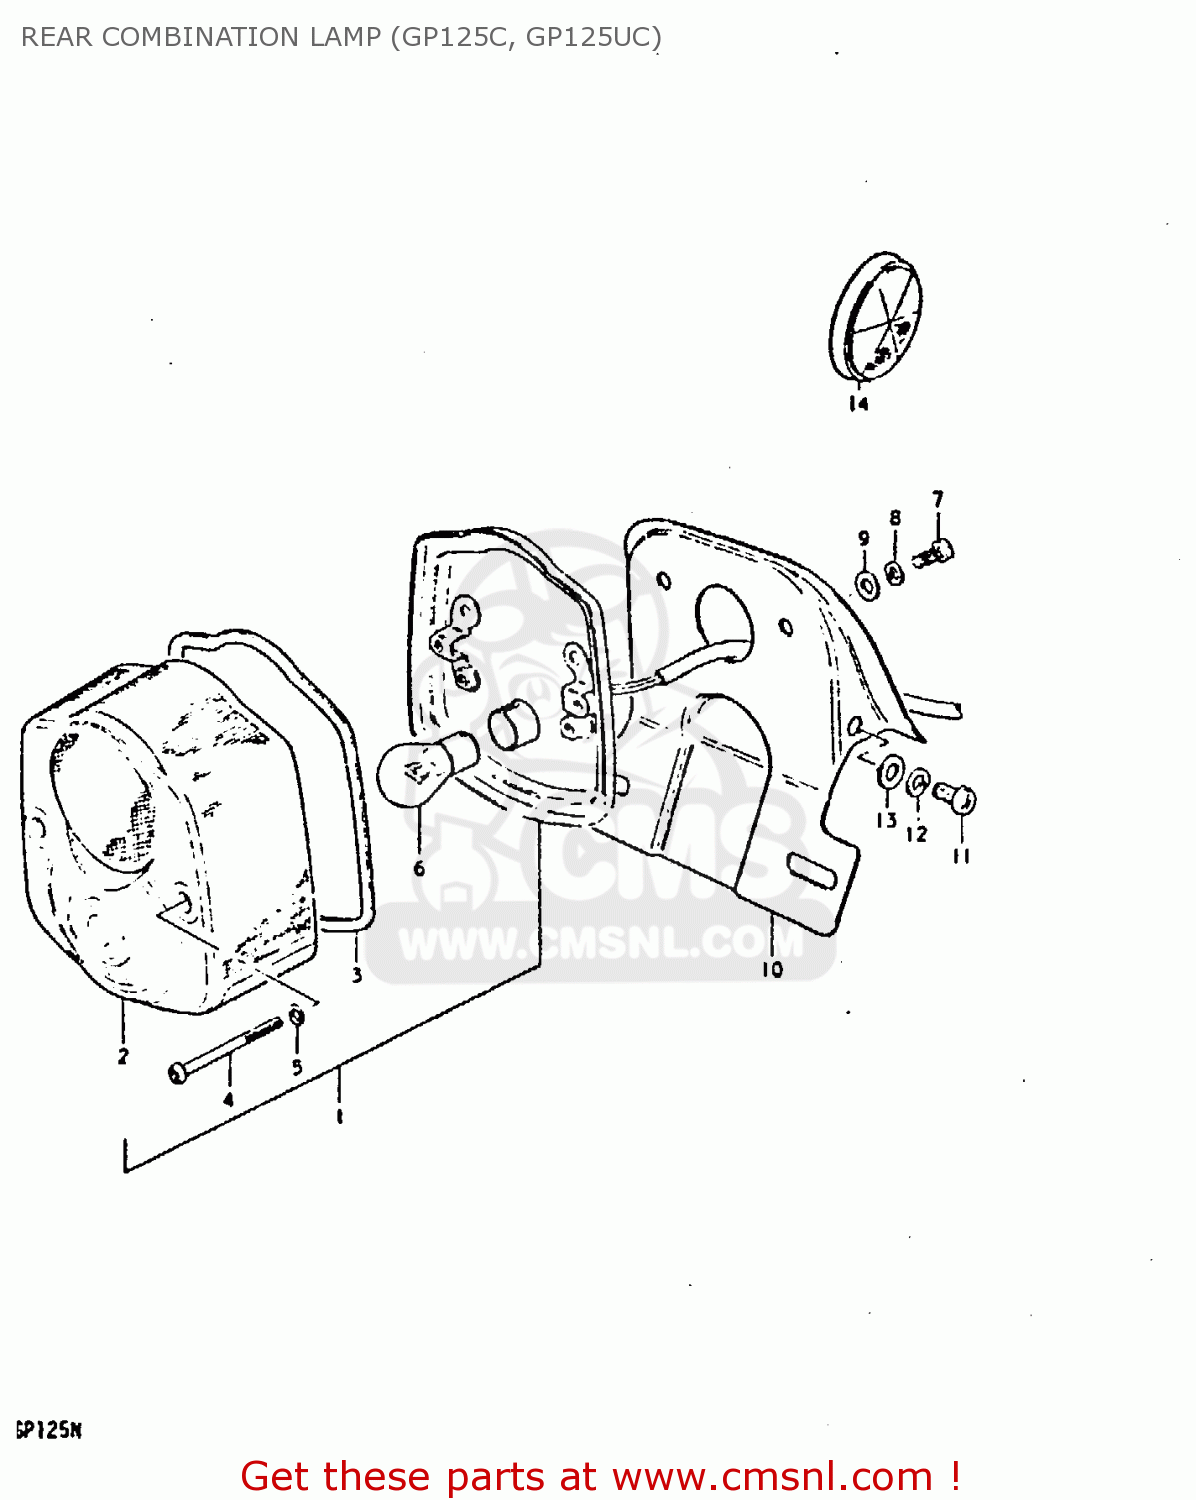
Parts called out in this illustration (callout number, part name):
1	LAMP ASSY, REAR COMBINATION
2	LENS
3	GASKET (NAS)
4	SCREW
5	GASKET (NAS)
6	BULB(6V10/3W,STANLEY,A4854H)
7	BOLT
8	LOCK WASHER
9	WASHER
10	BRACKET
11	SCREW
12	LOCK WASHER
13	WASHER
14	REFLEX REFLECTOR,FR
